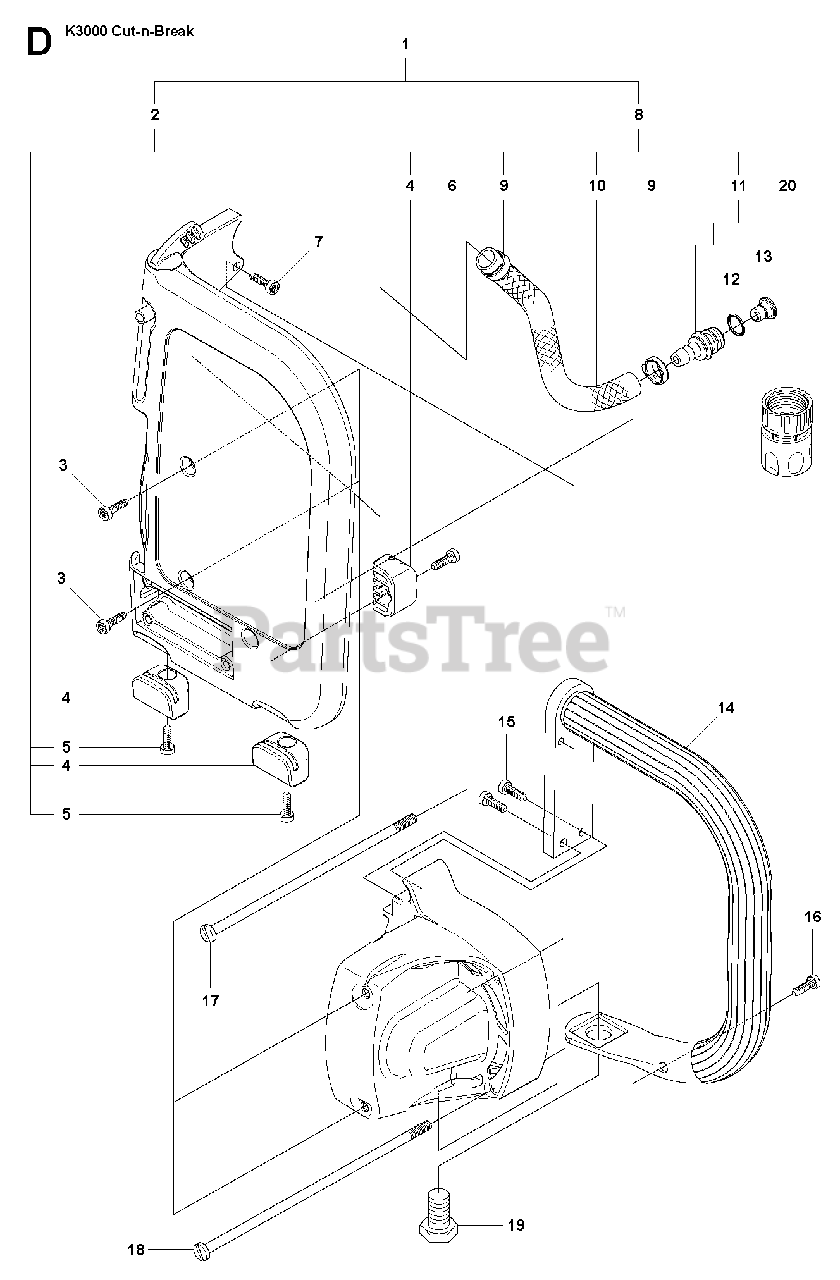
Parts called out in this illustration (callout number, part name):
5	SCREW ITXSCT
6	SCREW ITXSCT
7	SCREW ITXSCM
8	HOSE KITIncl. 9 - 11, 20
9	HOSE CLAMP
12	O-RING
15	SCREW ITXSCM
16	SCREW ITXSCT
